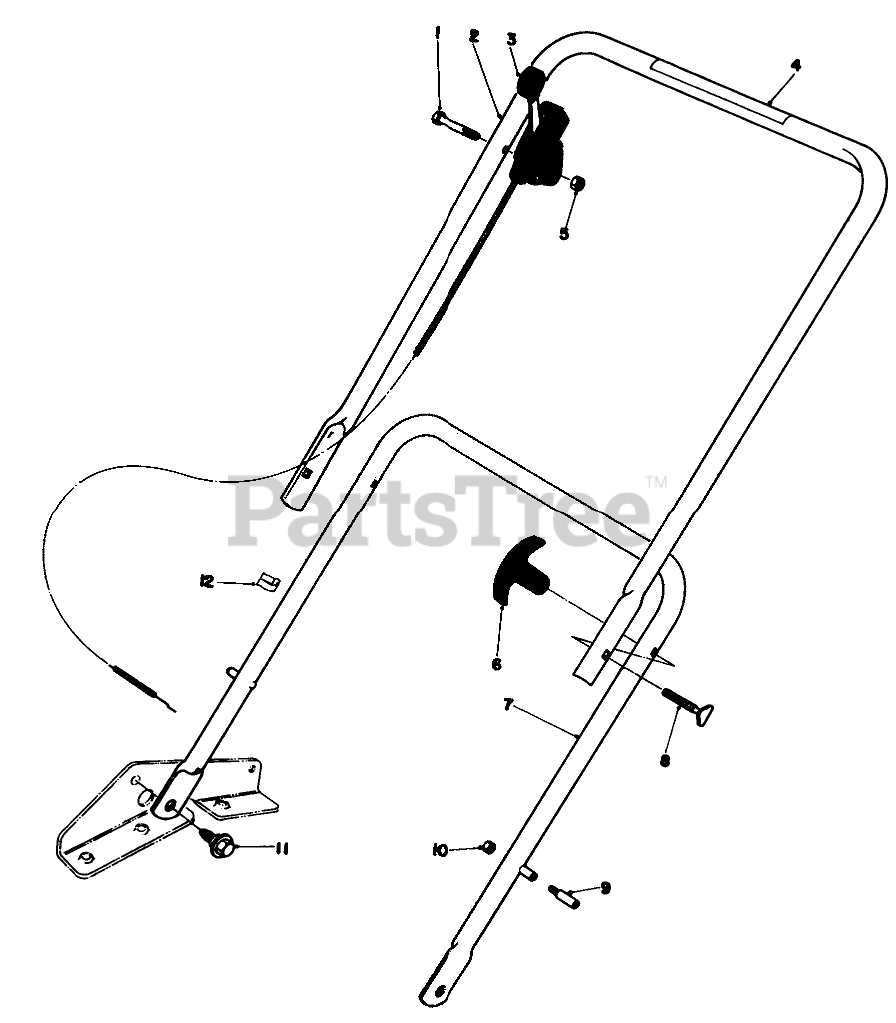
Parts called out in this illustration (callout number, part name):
1	SCREW-HH
2	Upper Handle
3	Throttle Control
4	Decal
5	NUT-LOCK
7	LOWER HANDLE ASM SP
8	HANDLE SCREW
9	HANDLE PIN
10	Nut
11	SCREW-SHOULDER
